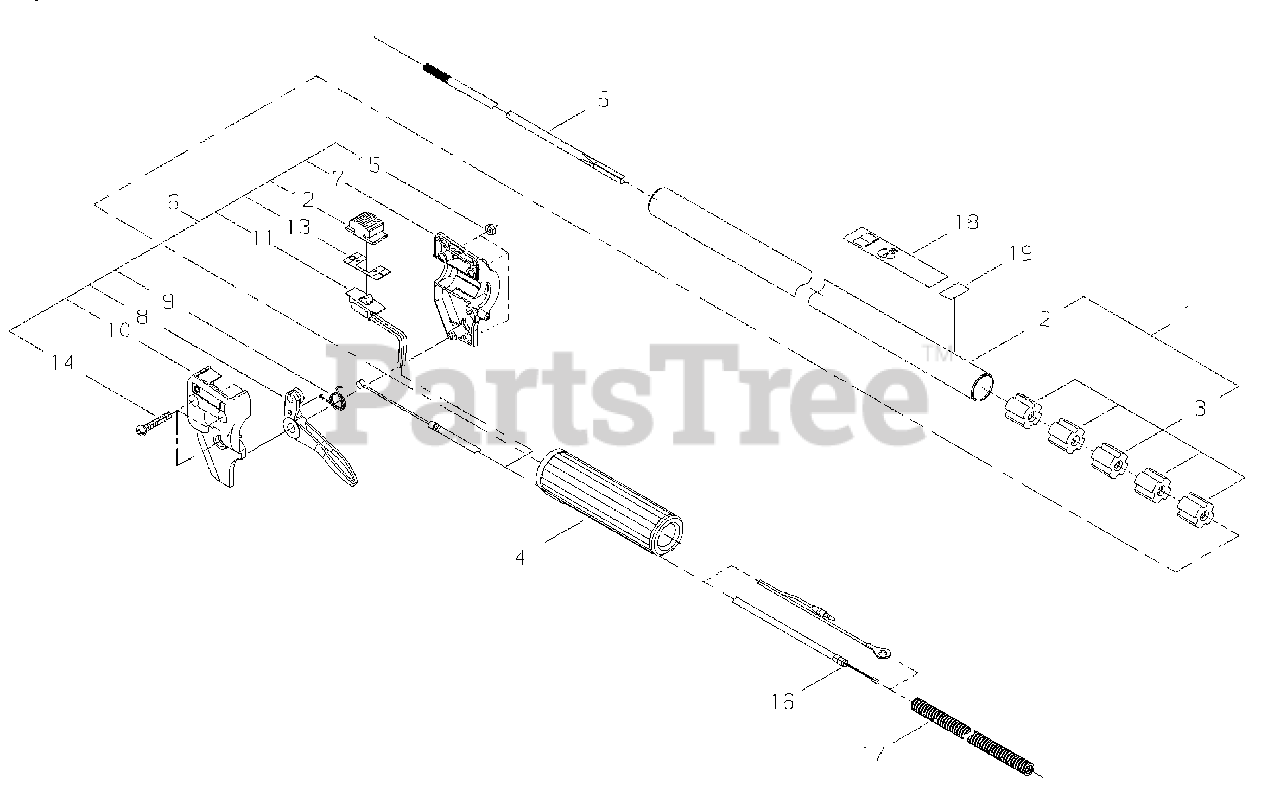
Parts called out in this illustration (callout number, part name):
1	MAIN PIPE ASSY
2	PIPE, MAIN
3	BUSHING
4	GRIP
5	MAINSHAFT
6	THROTTLE CONTROL ASSY
7	CONTROL HANDLE - RIGHT
8	TRIGGER, THROTTLE
9	SPRING, RETURN
10	CONTROL HANDLE - LEFT
11	SWITCH, ON-OFF
12	KNOB, SWITCH
13	PLATE, SWITCH
14	SCREW M5×30
15	NUT M5
16	CABLE, THROTTLE
17	TUBE, PLASTIC PROTECTIVE
18	LABEL, CAUTION (NON-BLADE CAPABLE)
19	LABEL, HANDLE
